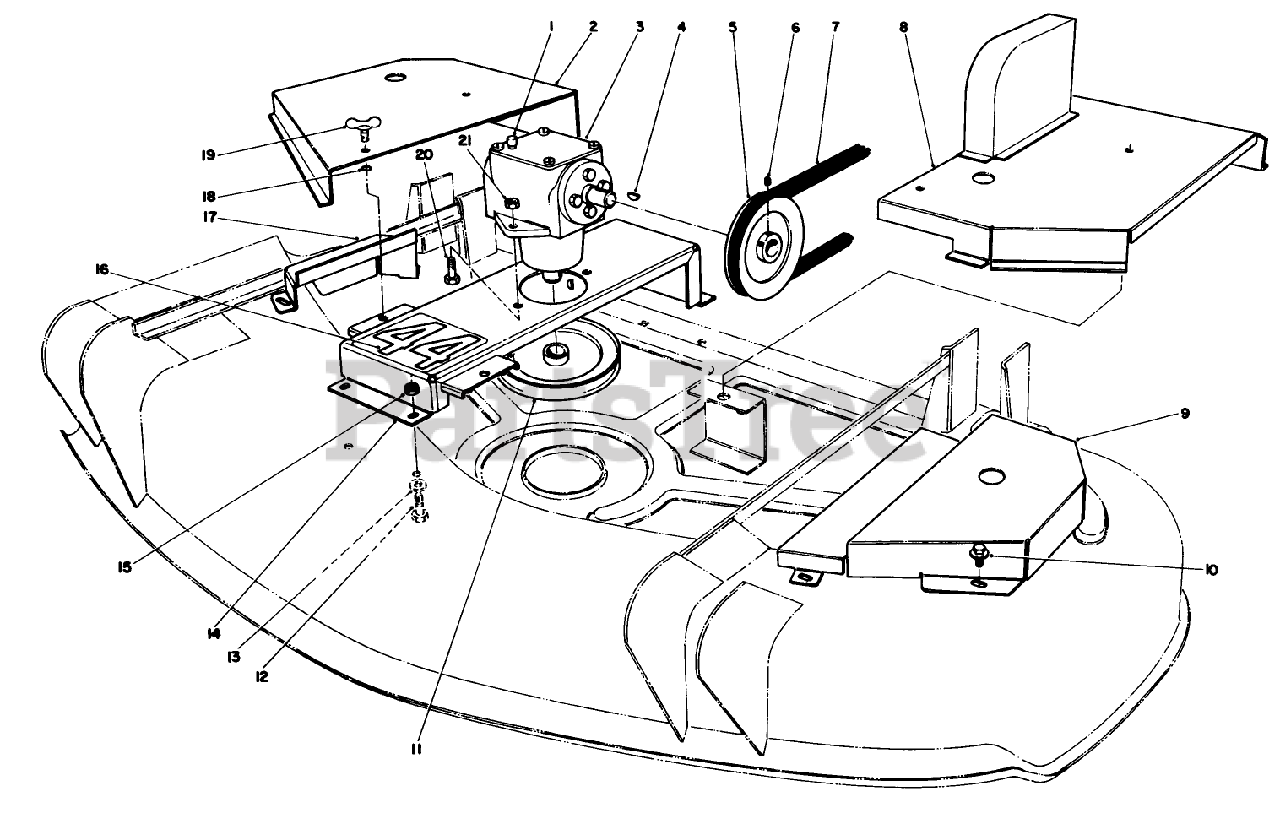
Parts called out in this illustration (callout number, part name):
4	KEY-WOODRUFF
6	SCREW-HH
7	V-BELT-DRIVE, DECK
10	SCREW-HHFTF
12	SCREW-HH
13	WASHER-PLAIN
15	NUT-LOCK, CONE
16	DECAL-44 INCH
18	RING-RETAINING
19	STUD-HEAD, WING
20	SCREW-HH
21	NUT-LOCK, CONE
